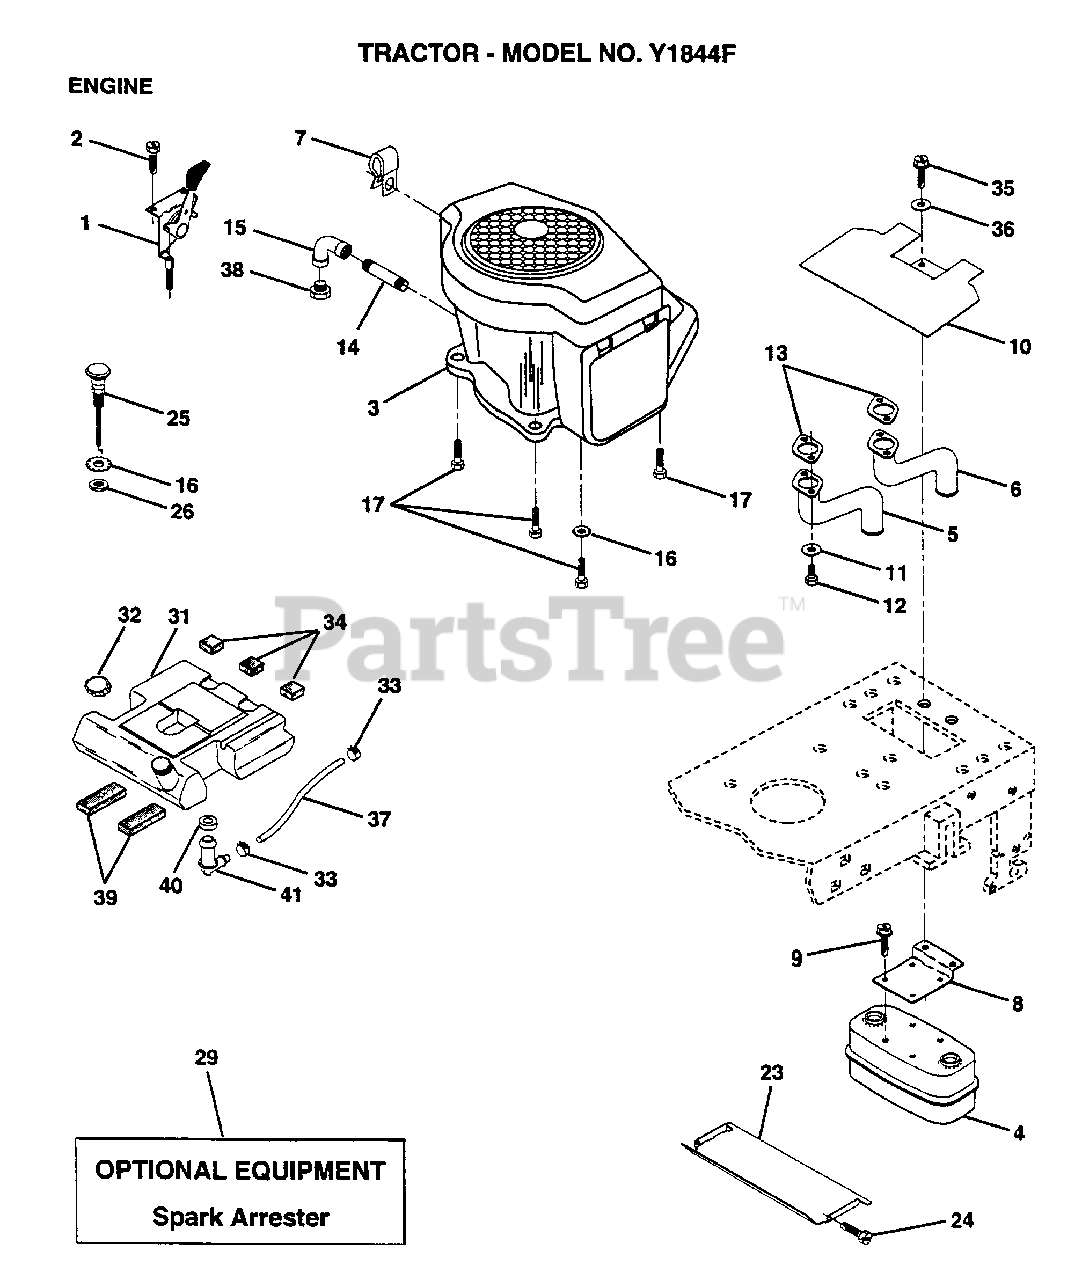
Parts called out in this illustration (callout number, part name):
1	CONTROL.THROTTL
2	SCREW LT
5	"TUBE,MANIFOLD LH"
6	"TUBE,MANIFOLD RH"
7	CLIP T
8	BRACKET MUFFLER
9	SCREW ST
10	SHIELD.HEAT.
11	LOCKWASHER
12	SCREW
14	PIPE NIPPLE LT
15	ELBOW
16	LOCKWASHER
17	SCREW LT
18	HEAT SHIELD
19	RETAINER LT
20	RETAINER LT
22	STUD.1/4.TURN
24	SCREW
32	CAP ASM FUEL
33	HOSE CLAMP
34	PAD-SPACER LT
35	SCREW
36	WASHER
37	FUEL LINE T
39	PAD IDLER TI
40	BUSHING OUTLET T
41	STEM.TANK.FUEL
81	NUT
